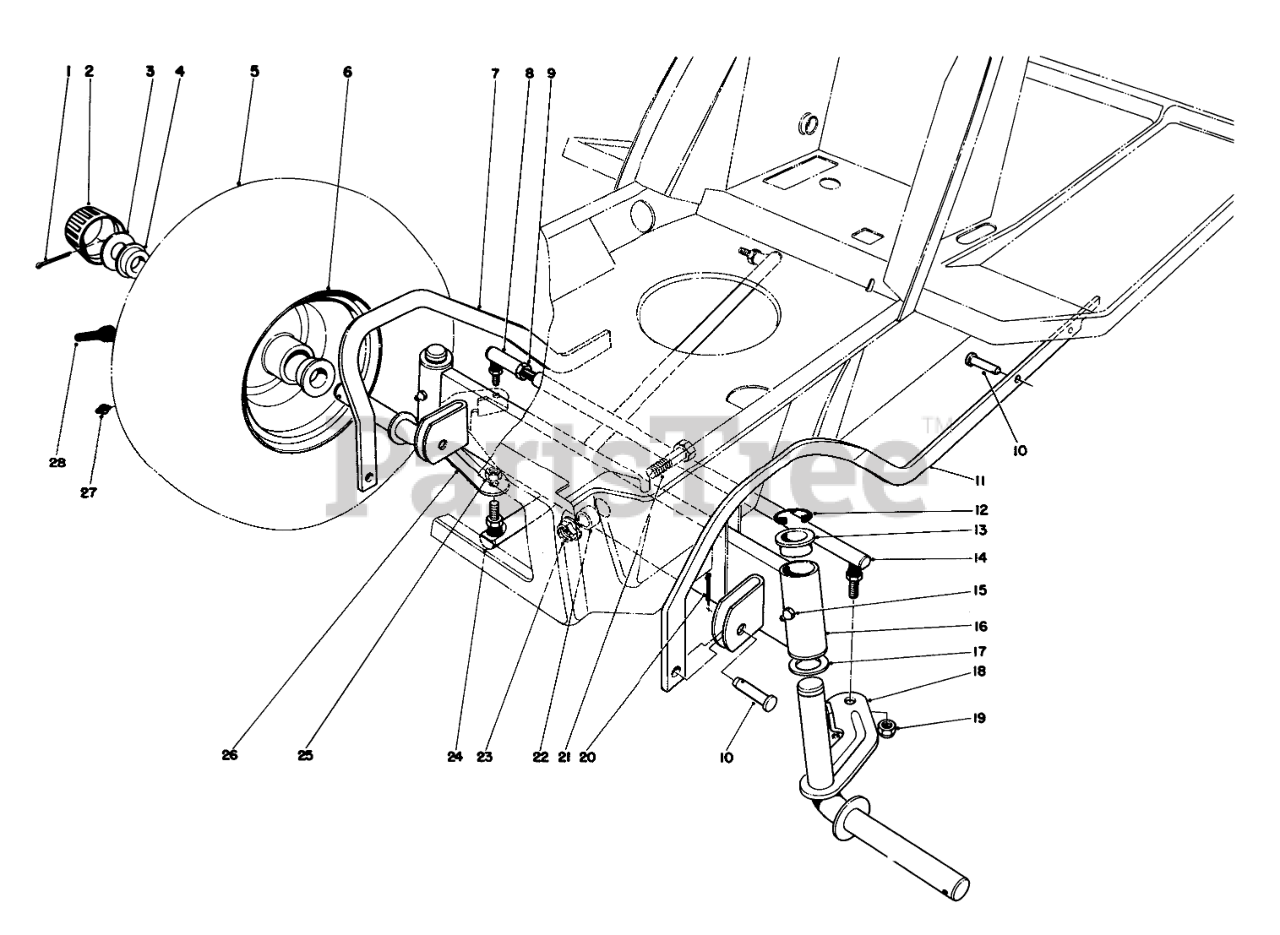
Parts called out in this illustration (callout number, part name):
1	PIN-COTTER
2	CAP-HUB
3	WASHER-PLAIN
4	Bearing
5	TIRE-FRONT
6	FRONT WHEEL
7	RH DECK PARALLEL LINK R
8	JOINT-BALL
9	NUT-JAM
10	PIN-CLEVIS
11	LH DECK PARALEL LNKR
12	E-RING
13	BEARING-FLANGE
14	Tie Rod Steering (Incl. Ref. #8 & 9)
15	GREASE FITTING
16	Front Axle (Incl. Ref. #13)
17	WASHER-THRUST
18	Spindle L.H.
19	NUT-LOCK, NI
20	PIN-COTTER
21	SCREW-HH
22	SPACER-AXLE, FRONT
23	NUT-HF
24	STEERING ARM B
25	NUT-HEX
26	SPINDLE WA RH B
27	FITTING-GREASE
28	STEM-VALVE
